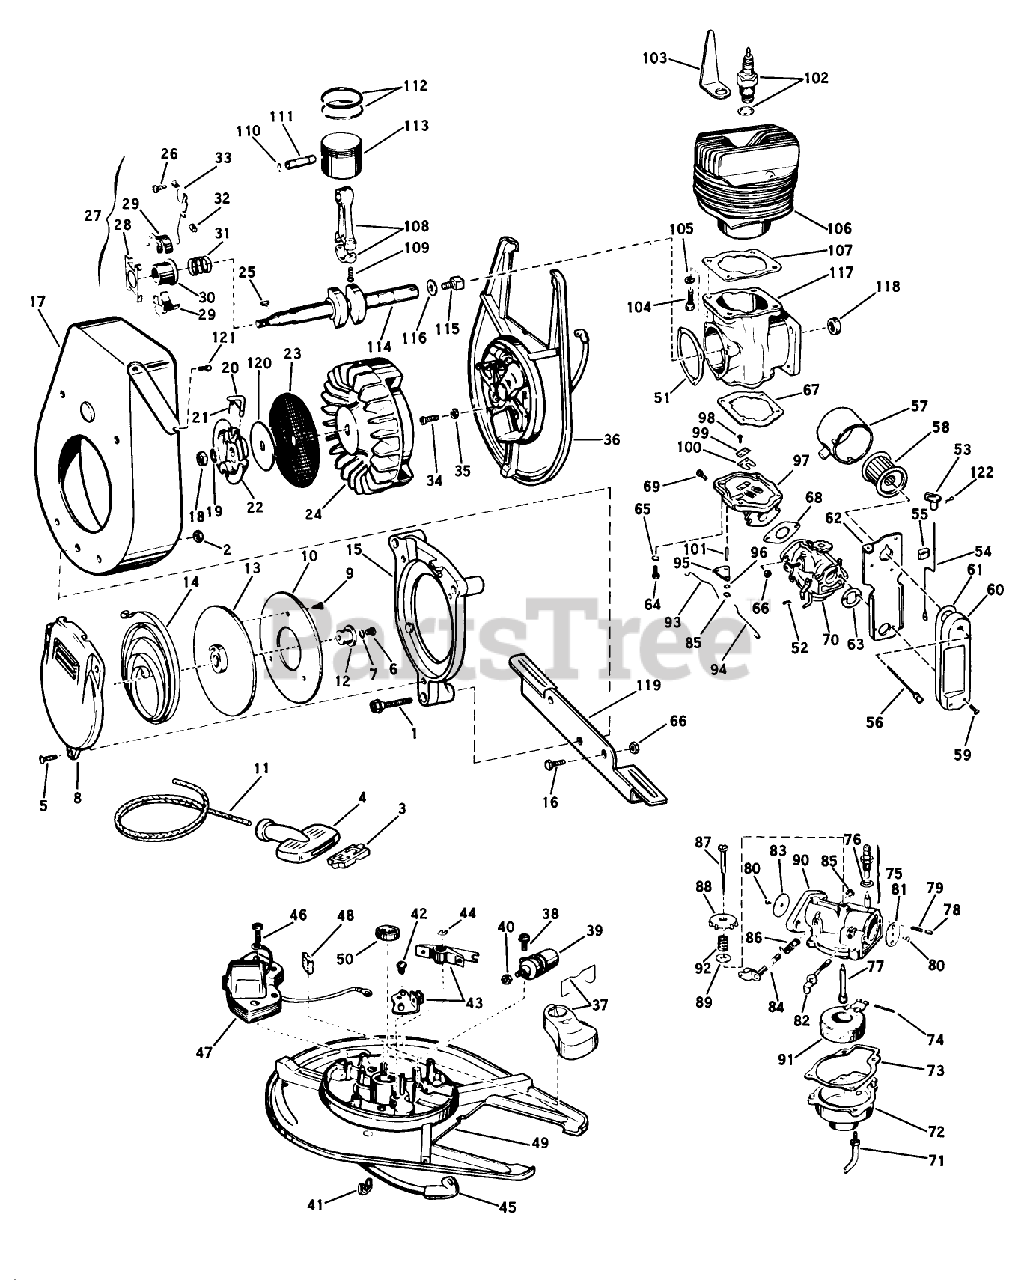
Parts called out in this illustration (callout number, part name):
10	Plate-Pulley
11	Rope-Starter
14	RECOIL SPRING
16	SCREW S
20	PIN - STARTER
30	COLLAR S
31	Spring-Governor
32	WEAR BLOCK S
33	GOVERNER LEVER AY
43	BREAKER AY. S
51	GASKET S
52	Cotter Pin
53	KNOB, CHOKE BAR
54	Choke Rod
55	Spring Clip
56	Screw-Thumb
59	Screw-Sems
60	Chamber-Intake
61	Gasket-Intake Chamber
62	Plate-Filter Attachment
64	SCREW S
67	Gasket-Reed Plate to Crankcase
68	GASKET S
69	SCREW S
71	Screw-Float Bowl to Carb.
80	Screw-Choke Disc
86	Spring-Throttle Shaft
87	NEEDLE AY. S
90	Carburetor Body
92	Spring-Ndl. Adj.
93	Rod-Governor
94	Link-Throttle
95	Bell Crank
99	PLATE-BACKUP, REED
101	Roll Pin
102	Spark Plug
106	Cylinder Sleeve Assembly
107	Gasket-Cylinder to Crankcase
109	Screw-Connecting Rod
112	Ring-Piston
114	Crankshaft
115	Screw-Square Head
116	WASHER, LOCK
119	Bracket-Wheel Scraper
121	SCREW S
122	Cotter Pin
